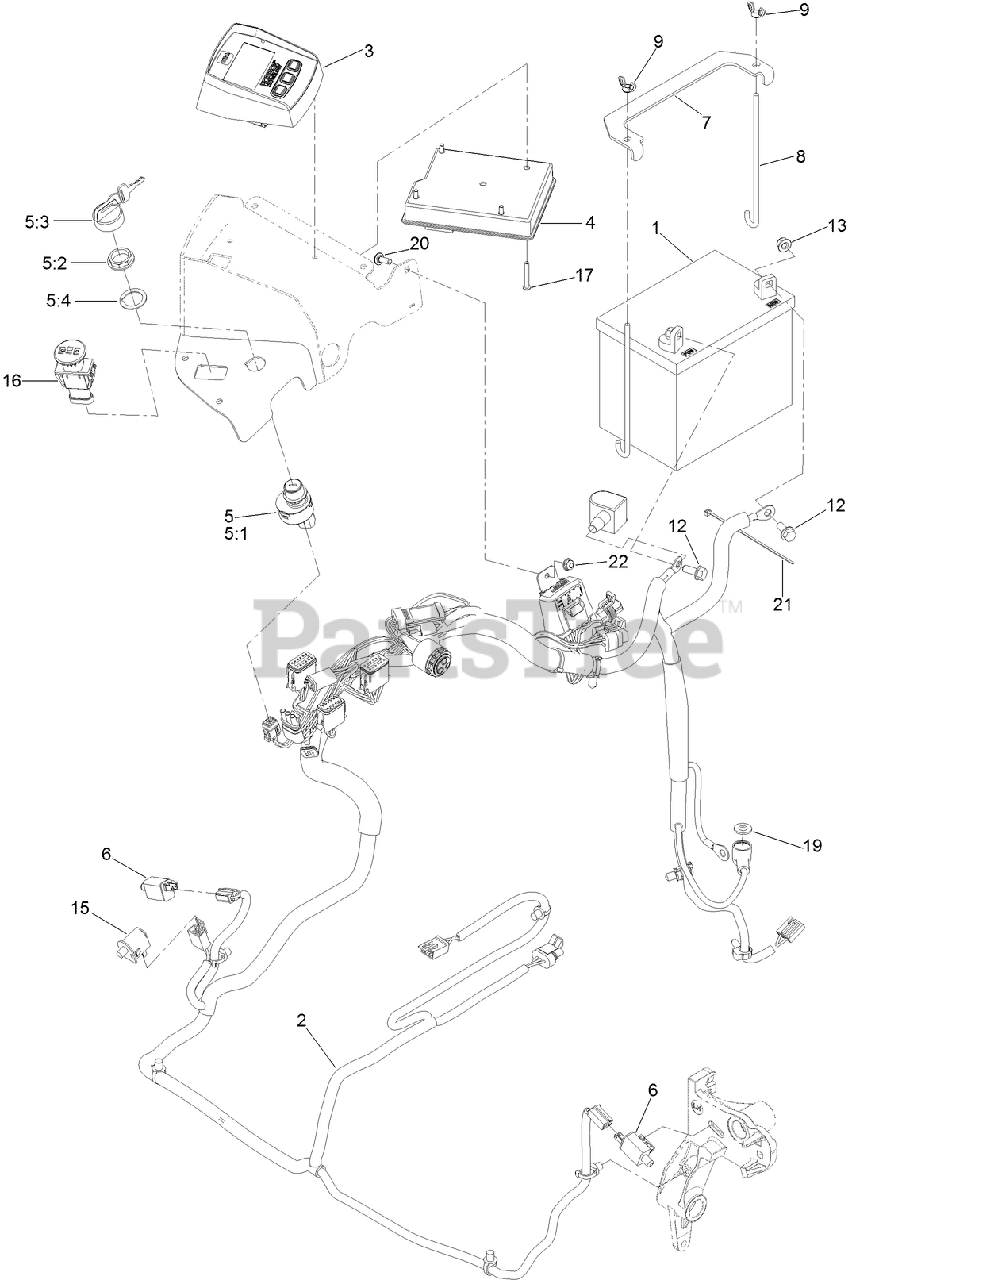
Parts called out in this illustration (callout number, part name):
1	BATTERY (340 CCA, WET)
2	HARNESS-WIRE
3	MODULE-HORIZON
4	MODULE-MCU
5	IGNITION SWITCH ASM
5:1	Deck ASM
5:2	NUT-MOUNTING
5:3	IGNITION KEY SET
5:4	WASHER-BACKUP
6	SWITCH
7	STRAP-TIE DOWN, BATTERY
8	BOLT-HOLDDOWN
9	WINGNUT
12	SCREW-HH
13	NUT-HF, NI
15	SWITCH-BAIL
16	SWITCH-PTO, SEALED
17	SCREW-PPH
19	WASHER-FLAT
20	BOLT-CARR
21	TIE-CABLE
22	NUT-HF
